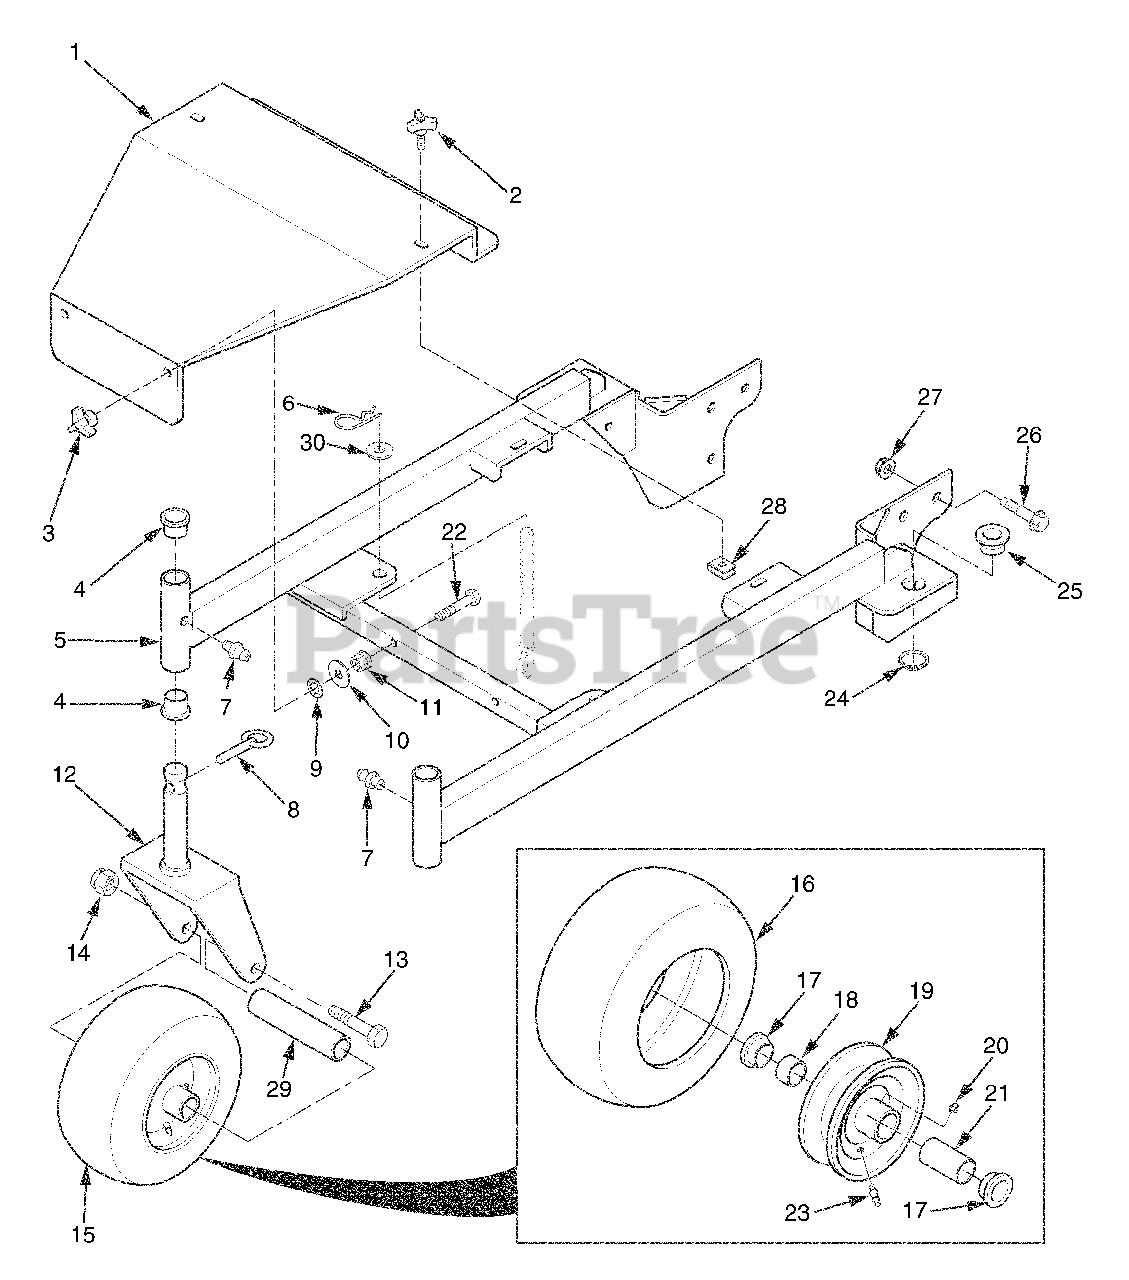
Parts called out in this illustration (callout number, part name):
1	Belt Cover With Decal
2	Knob With Stud
3	Knob, Deck Cover Mounting
4	Bushing, Caster
5	Frame Weldment, Deck Mounting - 36"
6	Hair Pin Cotter, .177" x 3-1/4"
7	Grease Fitting Str. 1/4-28 Self Tap
8	Quick Pin, .438" Dia.
9	Nut, Push-On - 3/8" Dia.
10	Flatwasher, 3/8" (.391 x .938 x .105)
11	Nut, 3/8-16 Serrated Flange Hex Head
12	Yoke, Caster Wheel
13	Capscrew, Hex Head 1/2-13 x 6-1/2"
14	Locknut, 1/2-13 Elastic Stop
15	Wheel Assembly, Caster
16	Tire, 11 x 4.00-5
17	Retainer
18	Roller Bearing
19	Rim, 5.0" x 2.75"
20	Grease Fitting Str. 1/4-28
21	Roller Bearing .625 x 3.25"
22	Capscrew, Hex Head 3/8-16 x 2-1/4"
23	Tire Valve, Purchase Locally
24	Retaining Ring 1.50 Ext.
25	Bushing, Deck Adjustment Pin
26	Capscrew, 1/2-13 x 1" Serrated Flange Hex Head
27	Nut, 1/2-13 Spiralock
28	U-Nut, 3/8-16
29	Sleeve, Caster Wheel
30	Flatwasher, 5/8" - (.688 x 1.75 x .134)
